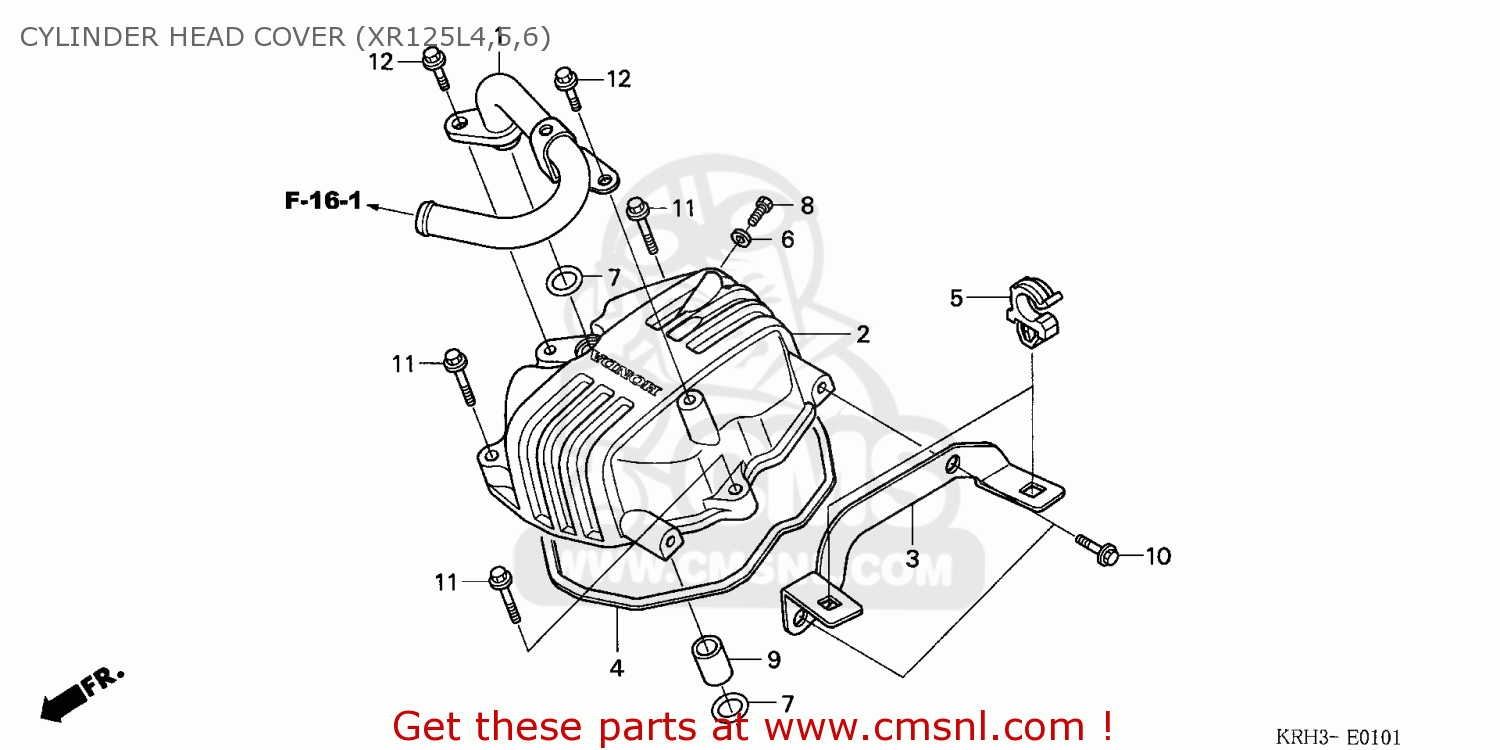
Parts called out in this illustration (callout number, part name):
1	PIPE COMP,AIR SUC
2	COVER,CYLN HEAD
3	PLATE,PB TUBE CLA
4	PACKING,HEAD COVE (NAS)
5	CLIP TUBE
6	WASHER, SEALING
7	O-RING 9.8X1.9
8	BOLT,HEX.,6X12
9	DOWEL PIN,10X12
10	BOLT,FLANGE 6X16
11	BOLT,FLANGE,6X28
12	BOLT,FLANGE,SH,6X16
